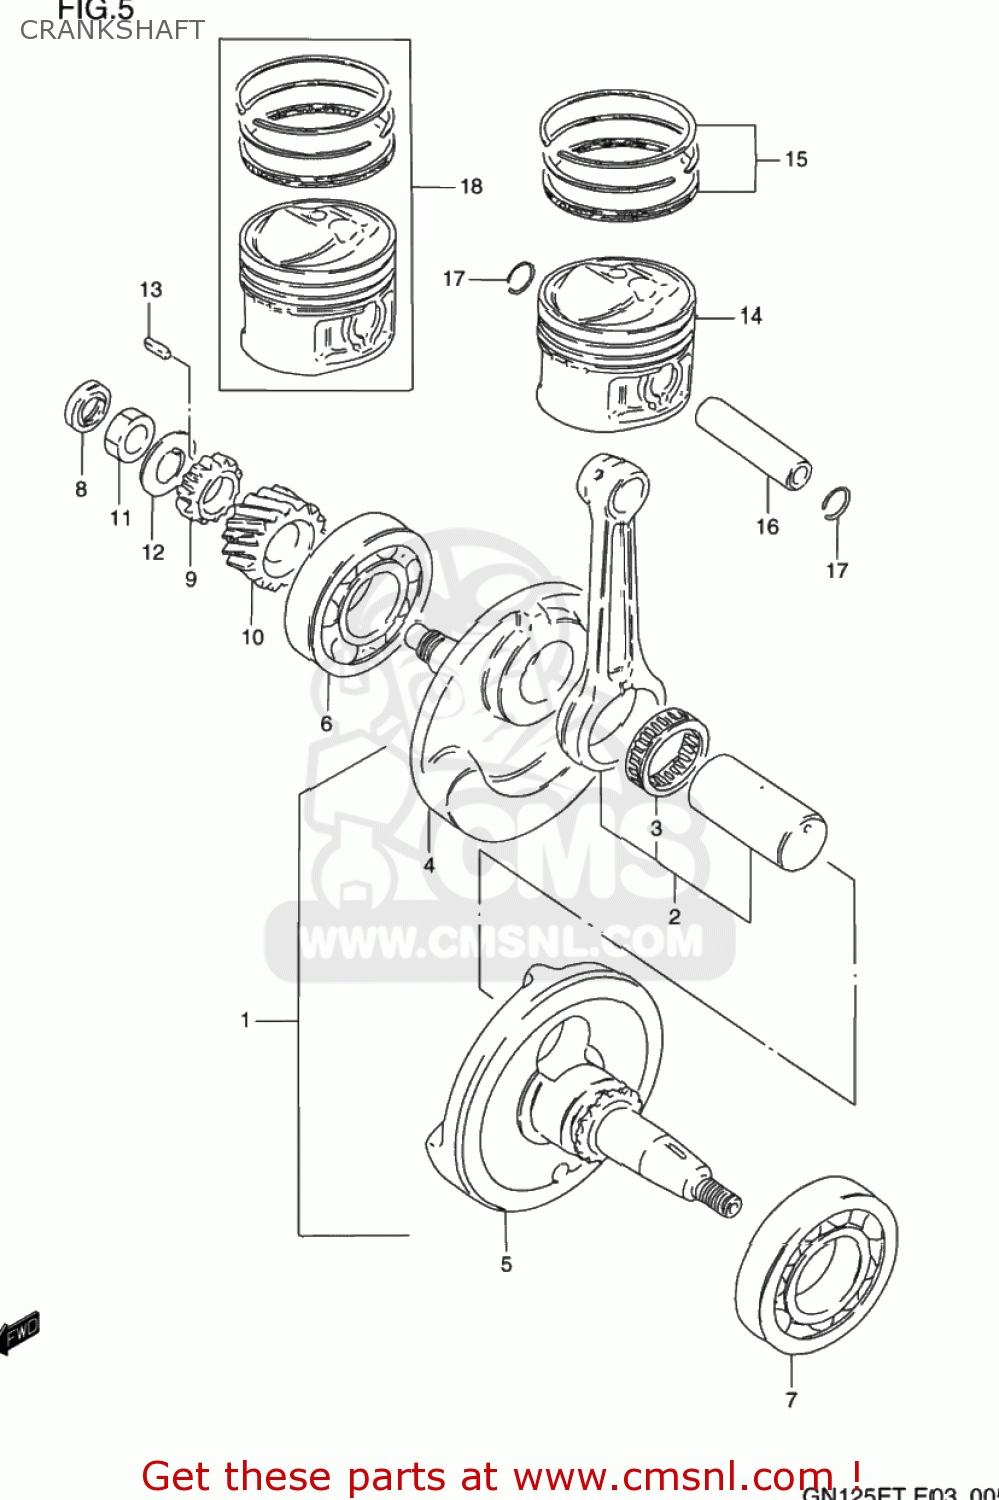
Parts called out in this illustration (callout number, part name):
1	CRANKSHAFT ASSEMBLY
2	CONNECTING ROD SET
3	BEARING
4	CRANKSHAFT
5	CRANKSHAFT,L
6	BEARING(28X68X18)
7	BEARING(35X72X17)
8	SEAL,OIL(12X21X7)
9	GEAR,OIL PUMP DRIVE
10	GEAR,PRIMARY DRIVE
11	NUT
12	WASHER
13	KEY
14	PISTON (STD)
15	RING SET,PISTON
16	PIN,PISTON
17	RING,SNAP 14MM
18	PISTON SET(OS:0.5)
